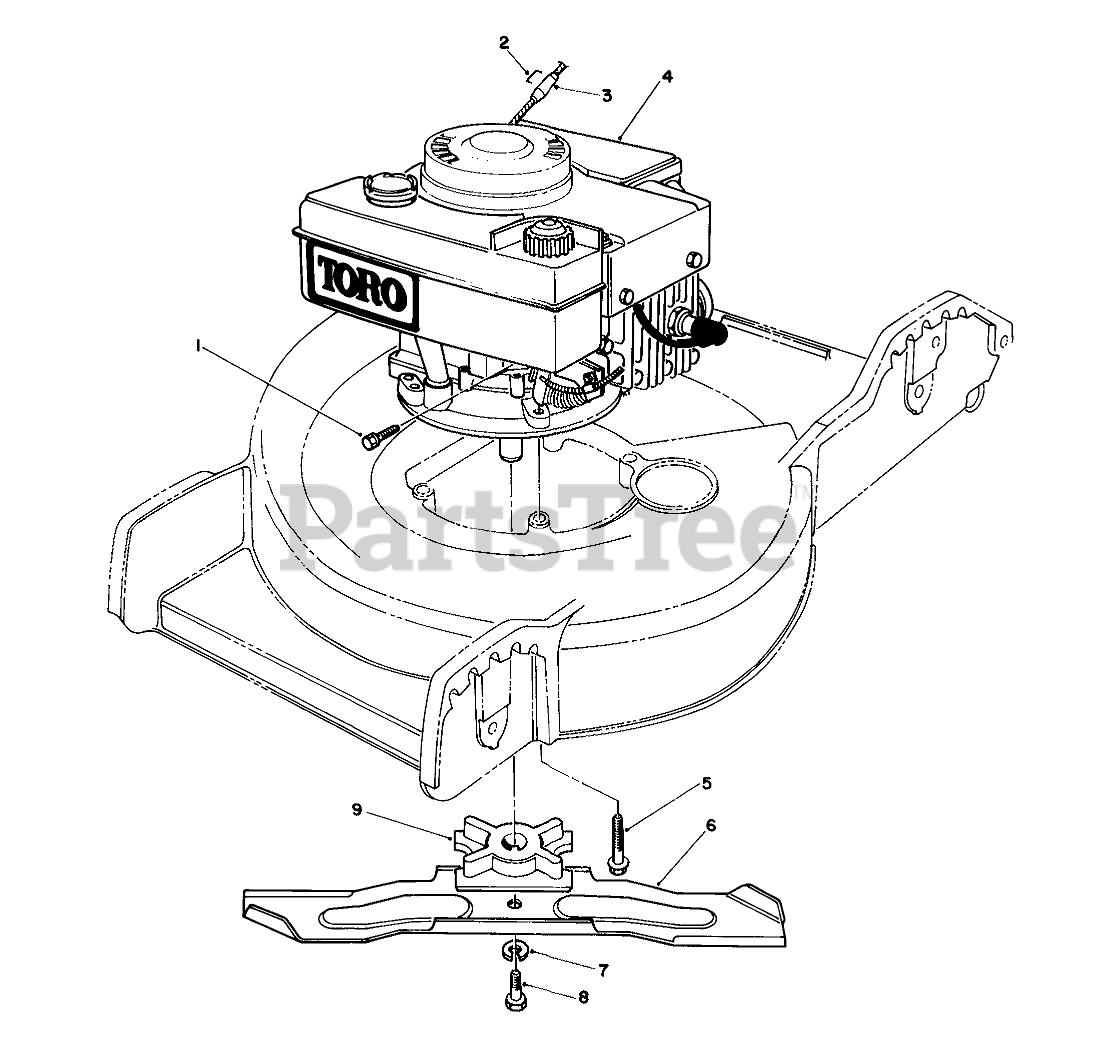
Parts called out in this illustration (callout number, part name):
1	SCREW-HH
2	Staple
3	Stop-Rope
5	3/8-16 X 2 CAPSCREW
6	Blade
7	WASHER-LOCK
8	SCREW-HH
9	BLADE RETAINER
